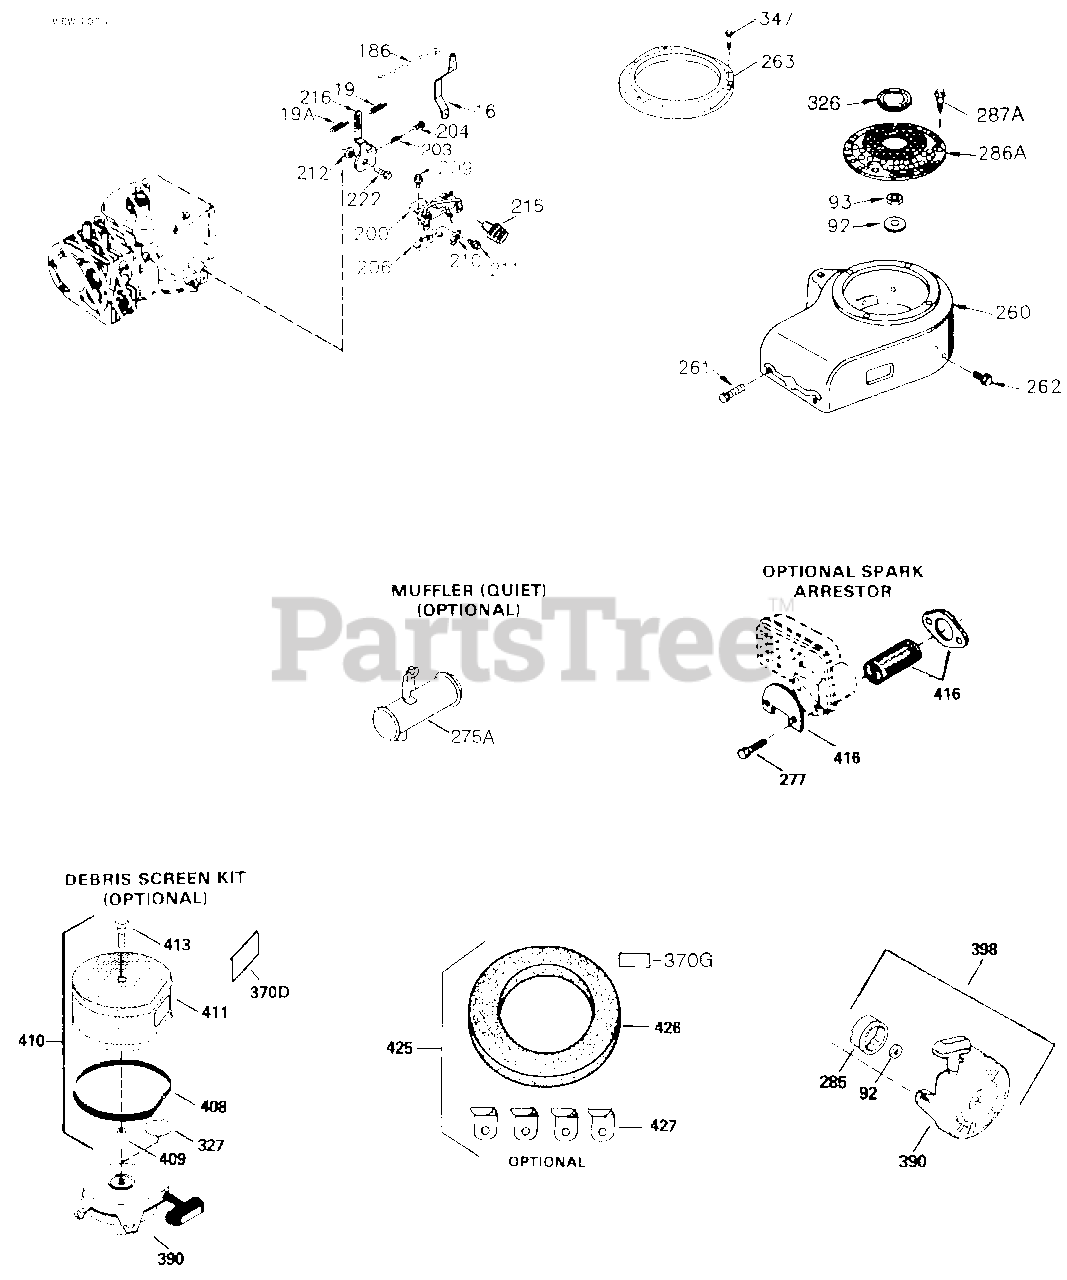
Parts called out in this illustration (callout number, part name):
72A	Oil Drain Plug
159	Rocker Arm Cover Gasket
306	Oil Fill Tube Gasket
361A	Screw, 1/4-20 x 1-13/32"
